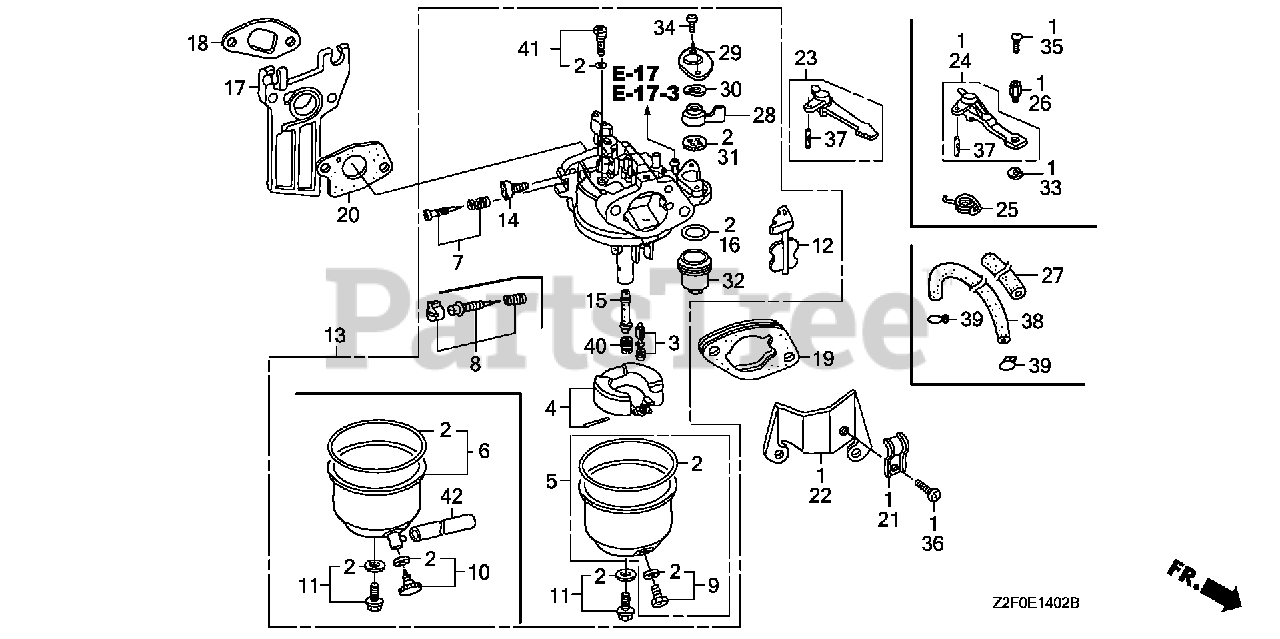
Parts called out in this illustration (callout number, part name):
2	GASKET SET
3	VALVE SET, FLOAT (SEAT NOT INCLUDED)
5	CHAMBER SET, FLOAT
8	SCREW SET, PILOT
9	SCREW SET, DRAIN
11	SCREW SET
13	CARBURETOR ASSY. (BE65B B/C)
14	SCREW, THROTTLE STOP
15	NOZZLE, MAIN
16	GASKET, FUEL STRAINER CUP
17	INSULATOR, CARBURETOR
18	GASKET, INSULATOR
19	SPACER, CARBURETOR
20	GASKET, CARBURETOR
23	LEVER, CHOKE (STD)
28	LEVER, PETCOCK
29	PLATE, LEVER SETTING
30	SPRING, PETCOCK LEVER
31	GASKET, PETCOCK
32	CUP, FUEL STRAINER
34	SCREW, PAN (3X6)
37	PIN, SPRING (2X12)
40	JET, MAIN (#65)
40	JET, MAIN (#68)
40	JET, MAIN (#70)
41	JET SET, PILOT (#35)
